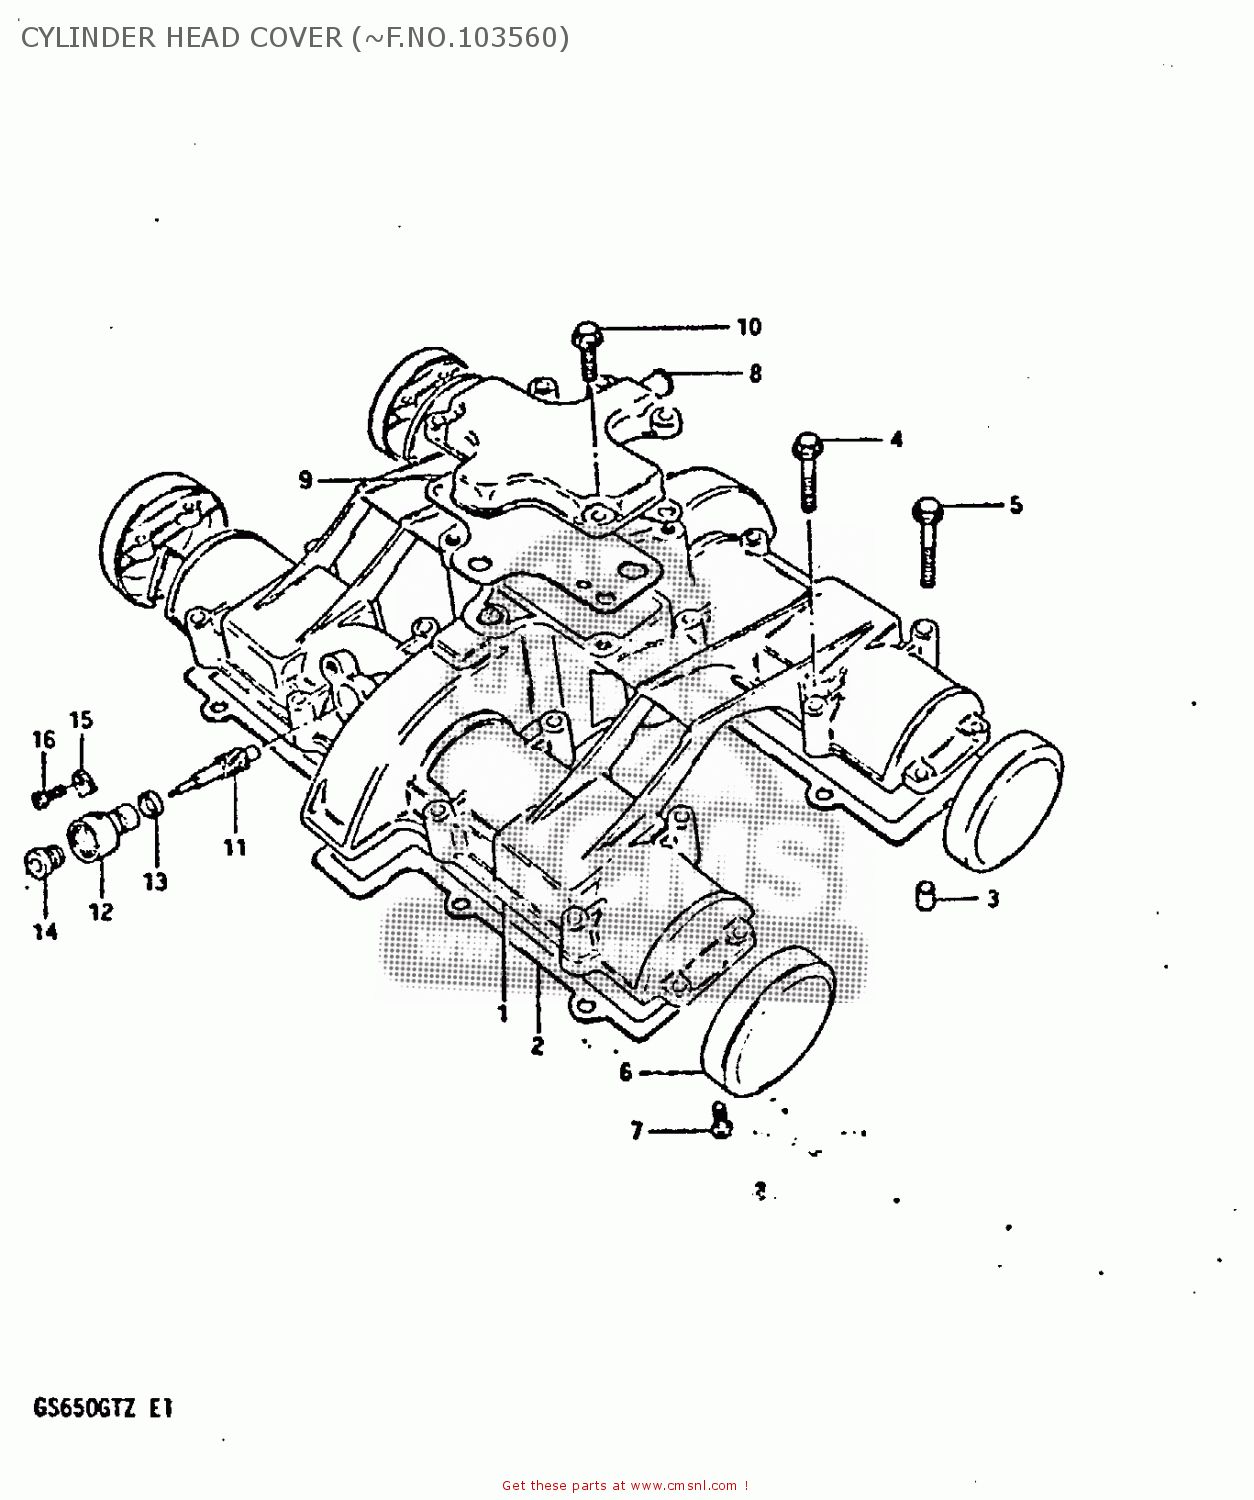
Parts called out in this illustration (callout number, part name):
1	COVER,CYLINDER HEAD
2	GASKET,CYLINDER HEAD COVER (MCA)
3	PIN(6.2X8X11)
4	BOLT
5	BOLT,UNDER
6	CAP,CYLINDER HEAD COVER
7	SCREW
8	COVER,BREATHER
9	GASKET (MCA)
10	BOLT,REAR
11	GEAR,TACHOMETER DRIVEN
12	SLEEVE,TACHOMETER DRIVE
13	SEAL,TACHOMETER DRIVEN
14	SEAL,OIL(5X12X8)
15	PLATE,TACH DRIVE GEAR SLEEVE
16	SCREW(5X12)
